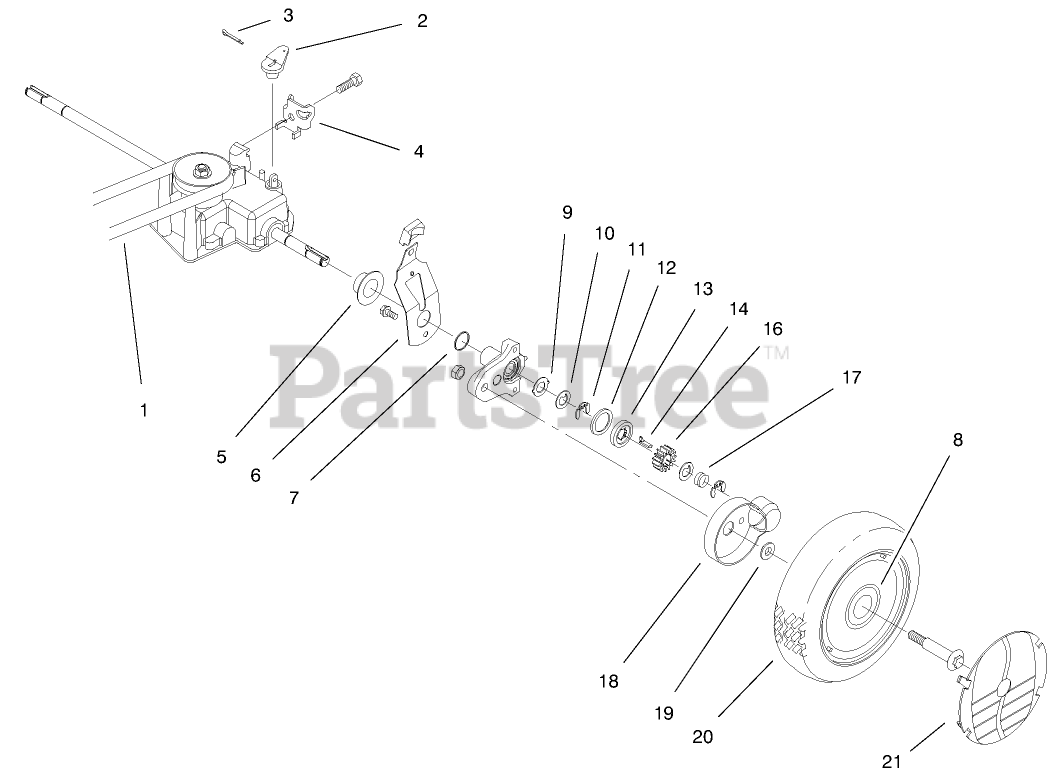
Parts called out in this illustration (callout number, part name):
1	V-BELT
2	LEVER-SHIFT
3	PIN-COTTER
4	CLAMP-CABLE
5	CAP-END
6	SPRING ARM ASM
7	O-RING
8	BUSHING
9	WASHER-ARM, PIVOT
10	WASHER-THRUST, KEYED
11	RING-RETAINING,CLIP
12	RING-FRICTION
13	WASHER-CLUTCH
14	KEY-ROCKING, LH
16	GEAR-PINION
17	SPRING-COMPRESSION
18	COVER-WHEEL
19	SPACER-COVER, WHEEL
20	WHEEL AND TIRE ASM
